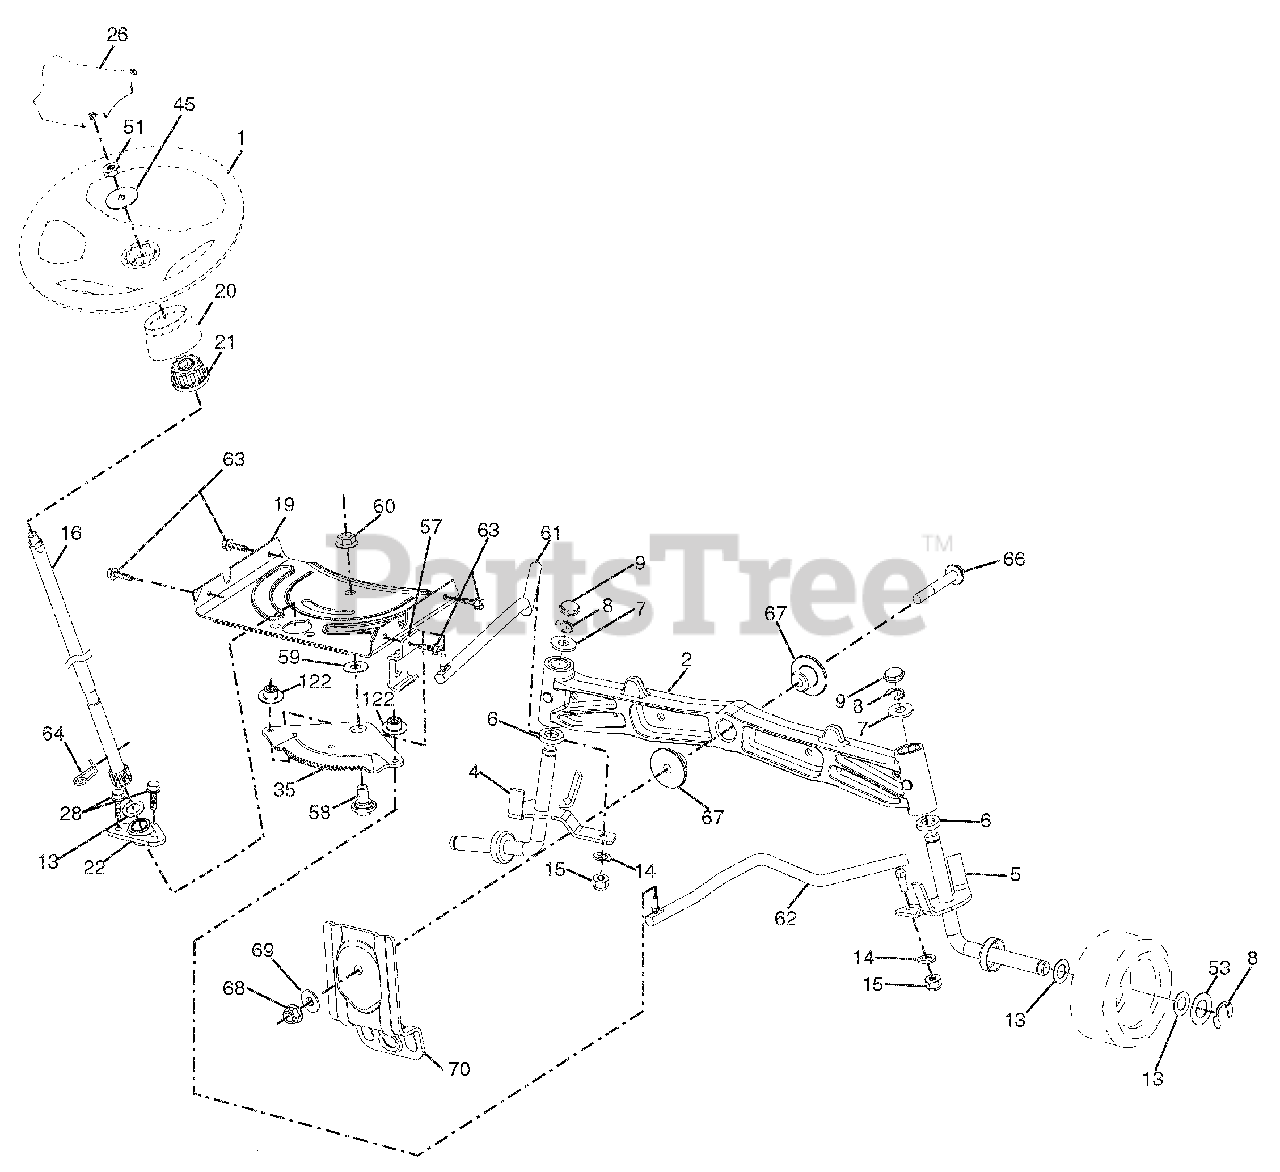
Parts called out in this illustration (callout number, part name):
1	WHEEL STEERING
2	AXLE.CAST IRON
4	SPINDLE.WELDED.LH.15"TEX
5	SPINDLE.WELDED.RH.15"TEX
6	WAHSER THRUST .75 X 1.230
7	WASHER.25/32 X 1-5/8 X 16GA.
8	RING.KLIP.#T5304-75
9	CAP.SPINDLE.FR.TOP.BLK.
13	WASHER.25/32 X 1 1/4 X 16 GA.
14	Washer, Lock 3/8
15	NUT.CROWNLOCK.3/8-24
16	SHAFT.STEER.3/4 TEX.NON-PLATED
19	PLATE.STEER.DDL.NLT/NGT
20	BOOT.STEERING
21	ADAPTER.WHEEL.STRG..760
22	STEERING SUPT. LOWER
26	CAP WHEEL STEERING HRS/SRS BLK
28	SCREW.HEXWSH THDR3/8-16X3/4.BL
35	GEAR SECTOR.PLATE.DDL.NLT/NGT
45	WASHER.9/16ID X 2-3/8OD.12GZIN
51	NUT.HEX.JAM.TOPLOCK.1/2-20 UNF
53	WASHER.HARDEN..793 X 1.637X060
57	BRACKET.UPSTOP.GT/LT.TEX
58	BOLT.SHOULDER.SECTOR.PIVOT.CFM
59	WASHER.THRUST.SECTOR.STEER.NLT
60	NUT.FLANGE LOCK.5/8-11
61	DRAGLINK.LH.BALLSTUD.DDL.
62	DRAGLINK.RH.BALLSTUD.DDL
63	SCREW.5/16-18X3/4.SMGML.TAP/BL
64	RETAINER.CLIP.SPRING.STEERING
66	BOLT.HEX.FGHD.7/16-14 X 3.SERR
67	BUSHING.PM.FRONT AXLE
68	NUT.LOCK.FLANGE.7/16-14.GR5
69	WASHER.1.5 X .505 X .118
70	BRACKET.DECK.SUSPENSION.FRONT
122	CAP GEAR SECTOR
